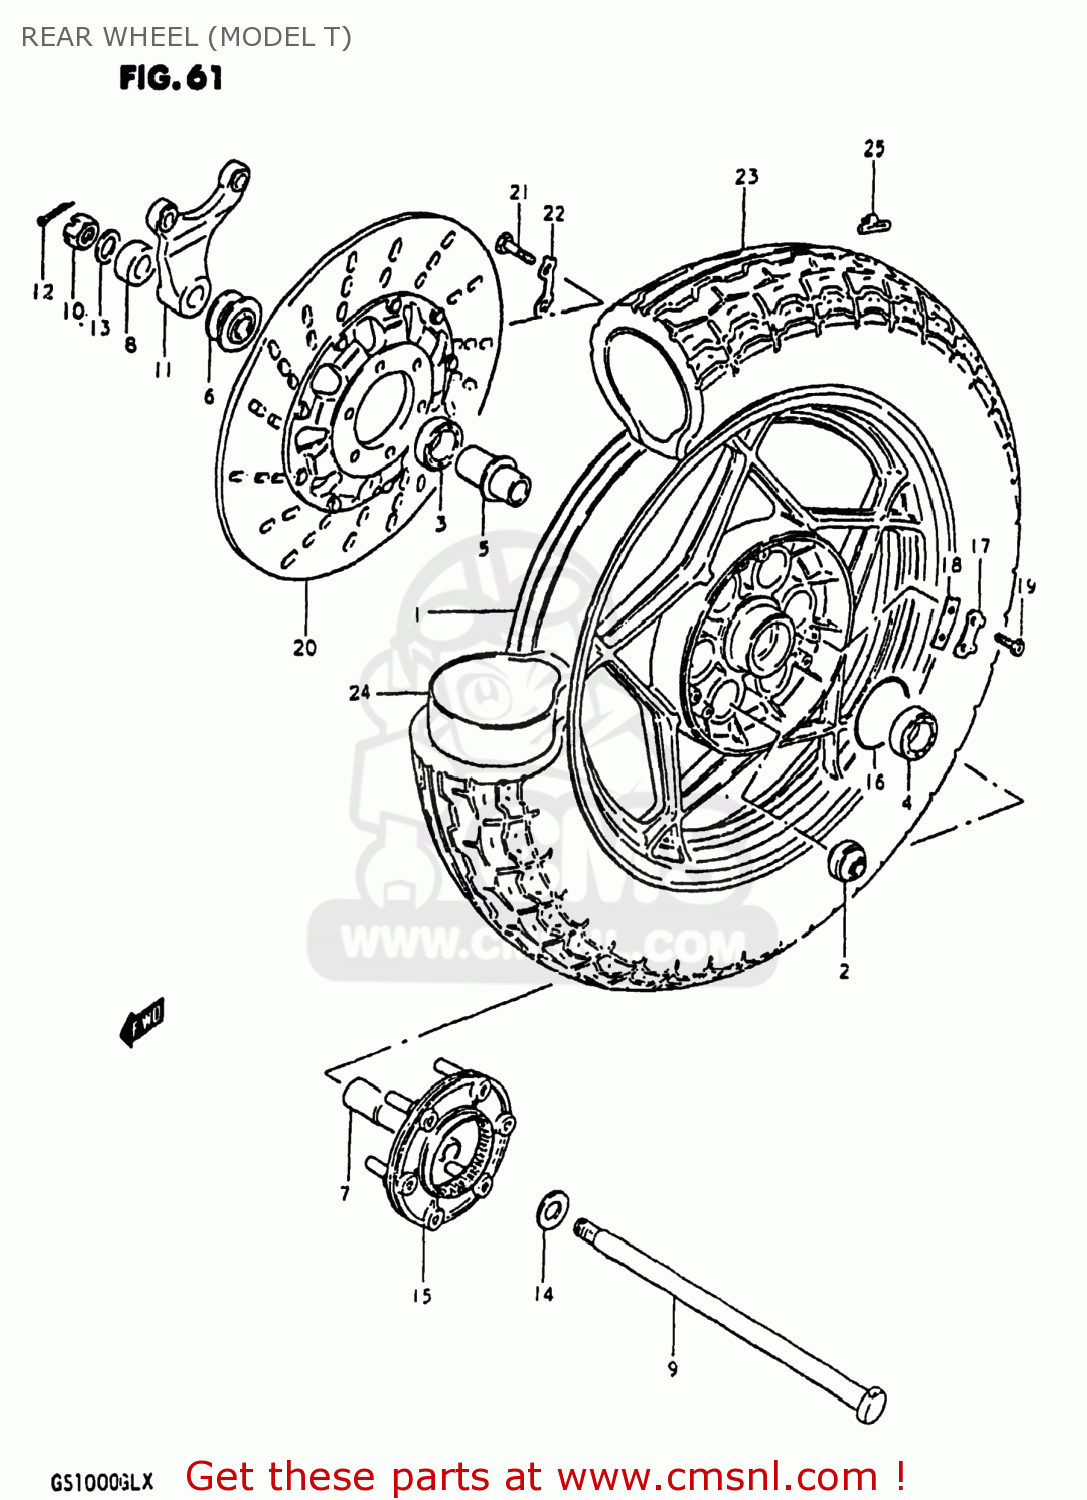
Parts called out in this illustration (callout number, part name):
1	CASTING WHEEL,REAR 2.50
2	BUSH
3	BEARING
4	BEARING
5	SPACER,REAR HUB BEARING
6	SPACER,REAR AXLE
7	SPACER,REAR AXLE,LEFT
8	SPACER (17X33X15.2)
9	AXLE,REAR
10	NUT
11	BRACKET,RR,CALIPER
12	PIN,COTTER
13	WASHER
14	WASHER (17.5X36X3.2)
15	JOINT ASSEMBLY,REAR HUB DRUM
16	O RING(D:2.1,ID:65)
17	WASHER (T:1.6)
18	WASHER,THRUST(T:1.6)
19	SCREW
20	DISC,RR BRAKE
21	BOLT(8X30)
22	WASHER
23	TIRE 4.50H17
24	TUBE ASSEMBLY,WHEEL,INNER
25	BALANCER,WHEEL
